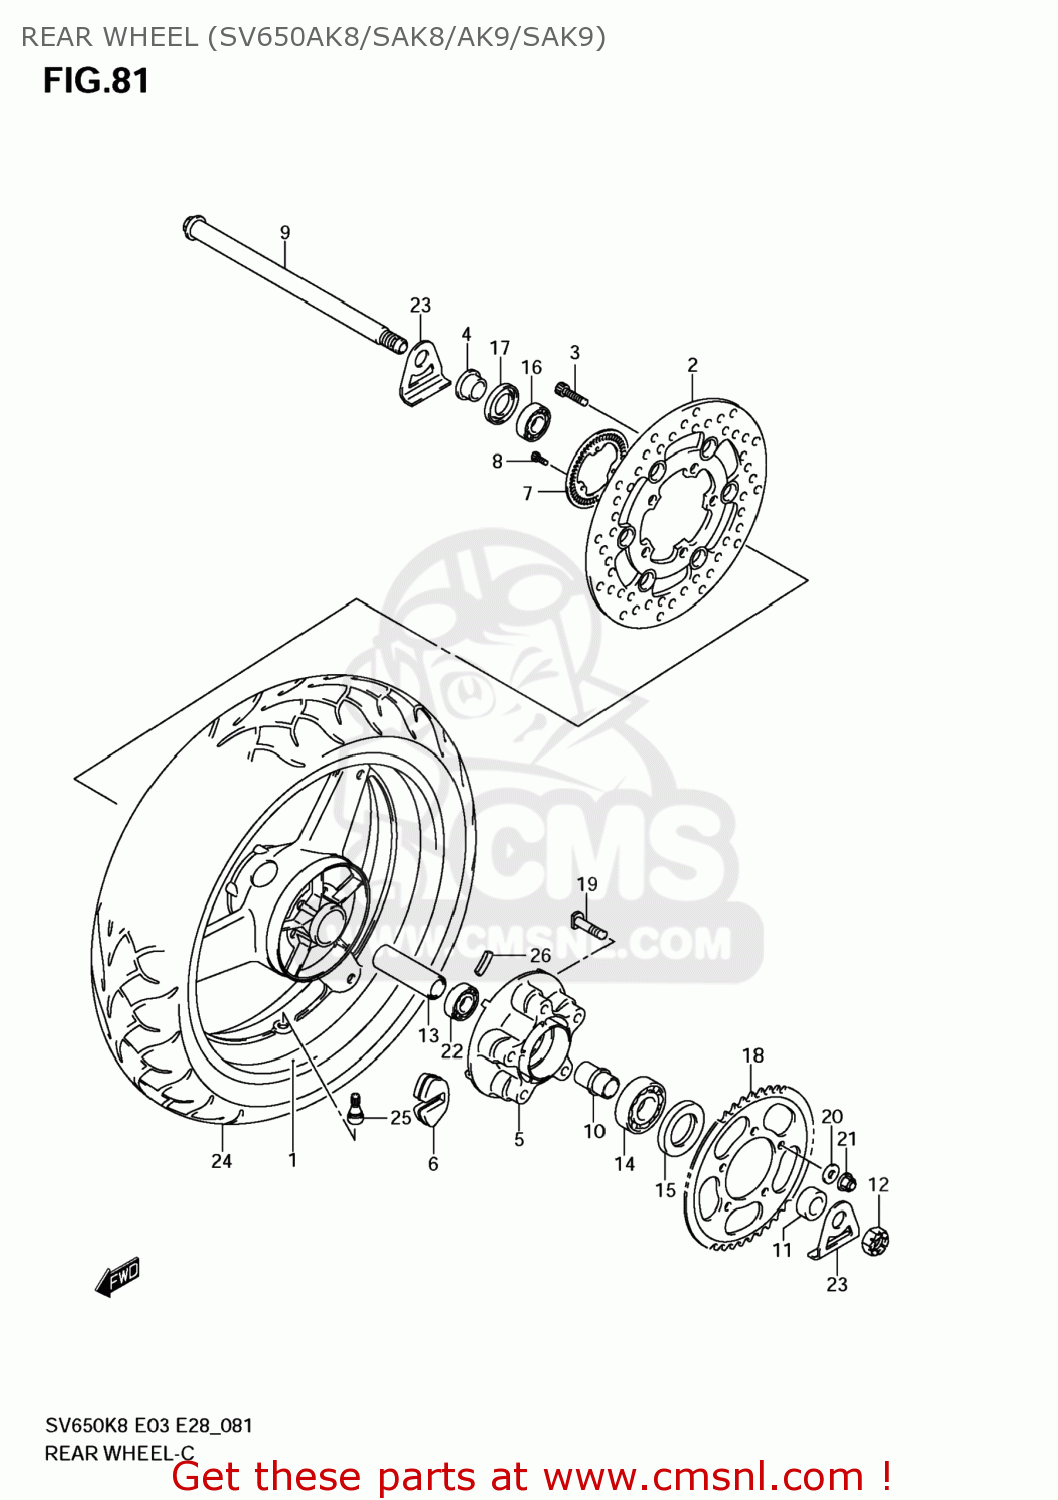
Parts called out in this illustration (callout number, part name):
1	WHEEL,RR(17M/CXMT4.50)
2	DISC,RR BRAKE
3	BOLT(8X33)
4	SPACER,RR AXLE,R
5	DRUM,RR SPROCKET MOUNTING
6	ABSORBER,RR HUB SHOCK
7	RING,SPEED SENSOR RR(50T)
8	BOLT
9	AXLE,RR
10	RETAINER,RR HUB BEARING
11	SPACER,RR AXLE,L
12	NUT
13	SPACER(20.5X28X88)
14	BEARING(20X47X14)
15	SEAL,OIL(28X47X7)
16	BEARING(25X62X17)
17	SEAL,OIL(35X62X8)
18	SPROCKET,RR(NT:45-525)
19	BOLT(10X47)
20	WASHER(10.5X22X2.3)
21	NUT
22	BEARING
23	WASHER,CHAIN ADJUSTER
24	TIRE,RR(160/60 ZR17M/C 69W)
25	VALVE ASSY,WHEEL RIM(TR412)
26	BALANCER,WHEEL(10G)
